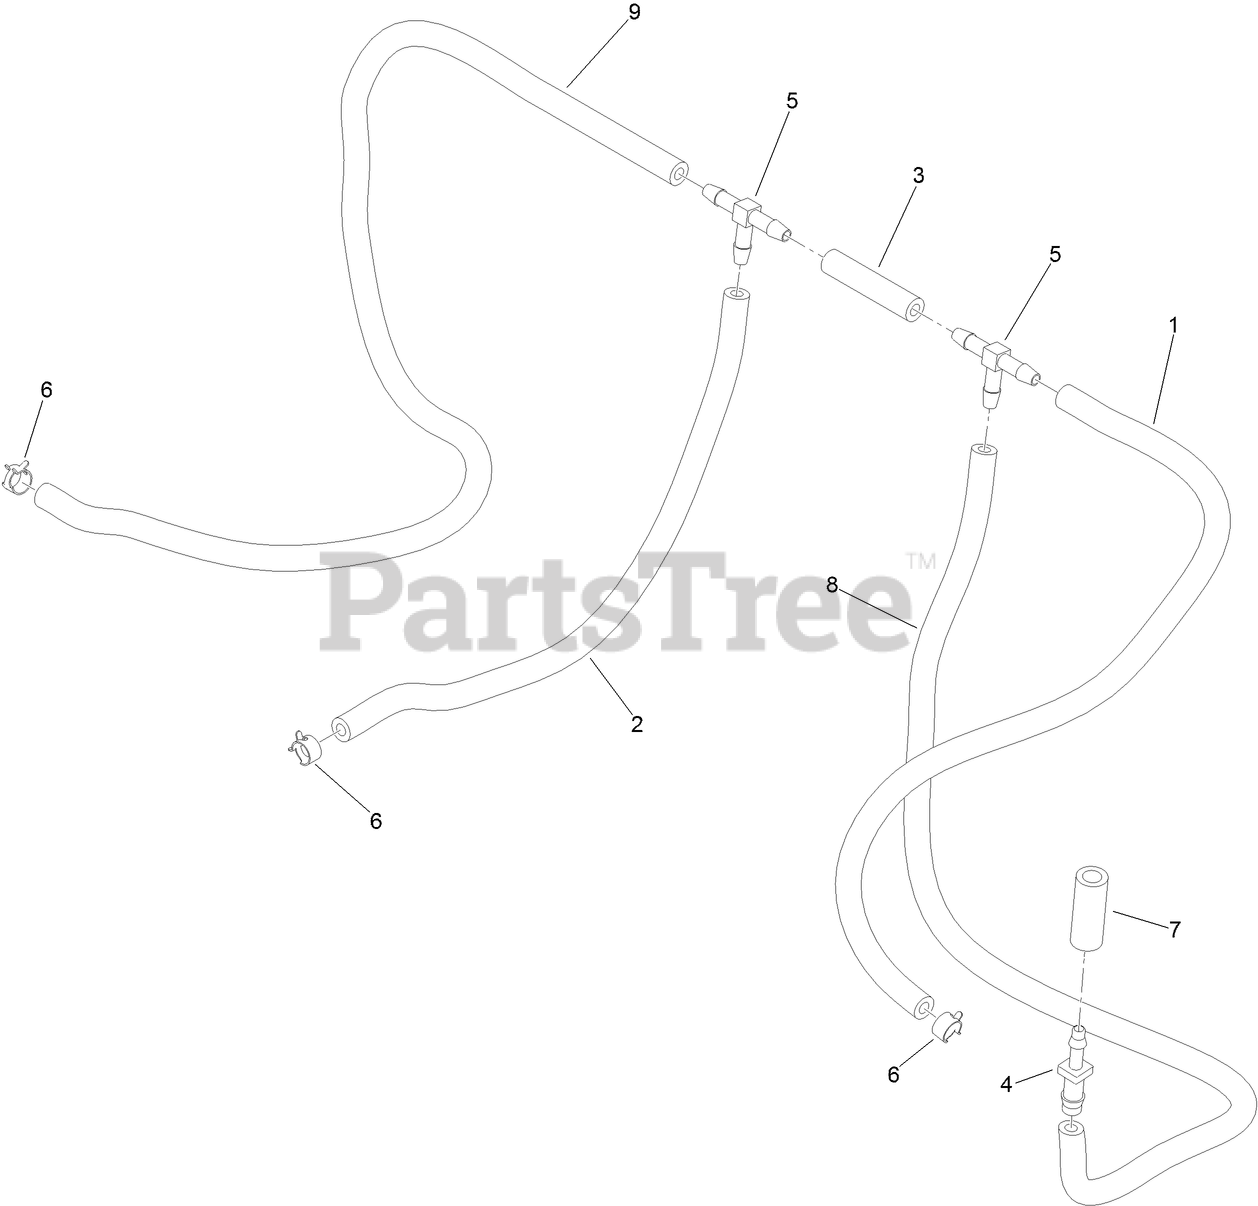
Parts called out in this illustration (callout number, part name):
1	HOSE-FUEL
2	HOSE-FUEL
3	HOSE-FUEL
4	FITTING-STRAIGHT
5	FITTING-TEE, BARBED
6	CLAMP-HOSE
7	HOSE-FUEL
8	HOSE-FUEL
9	HOSE-FUEL
